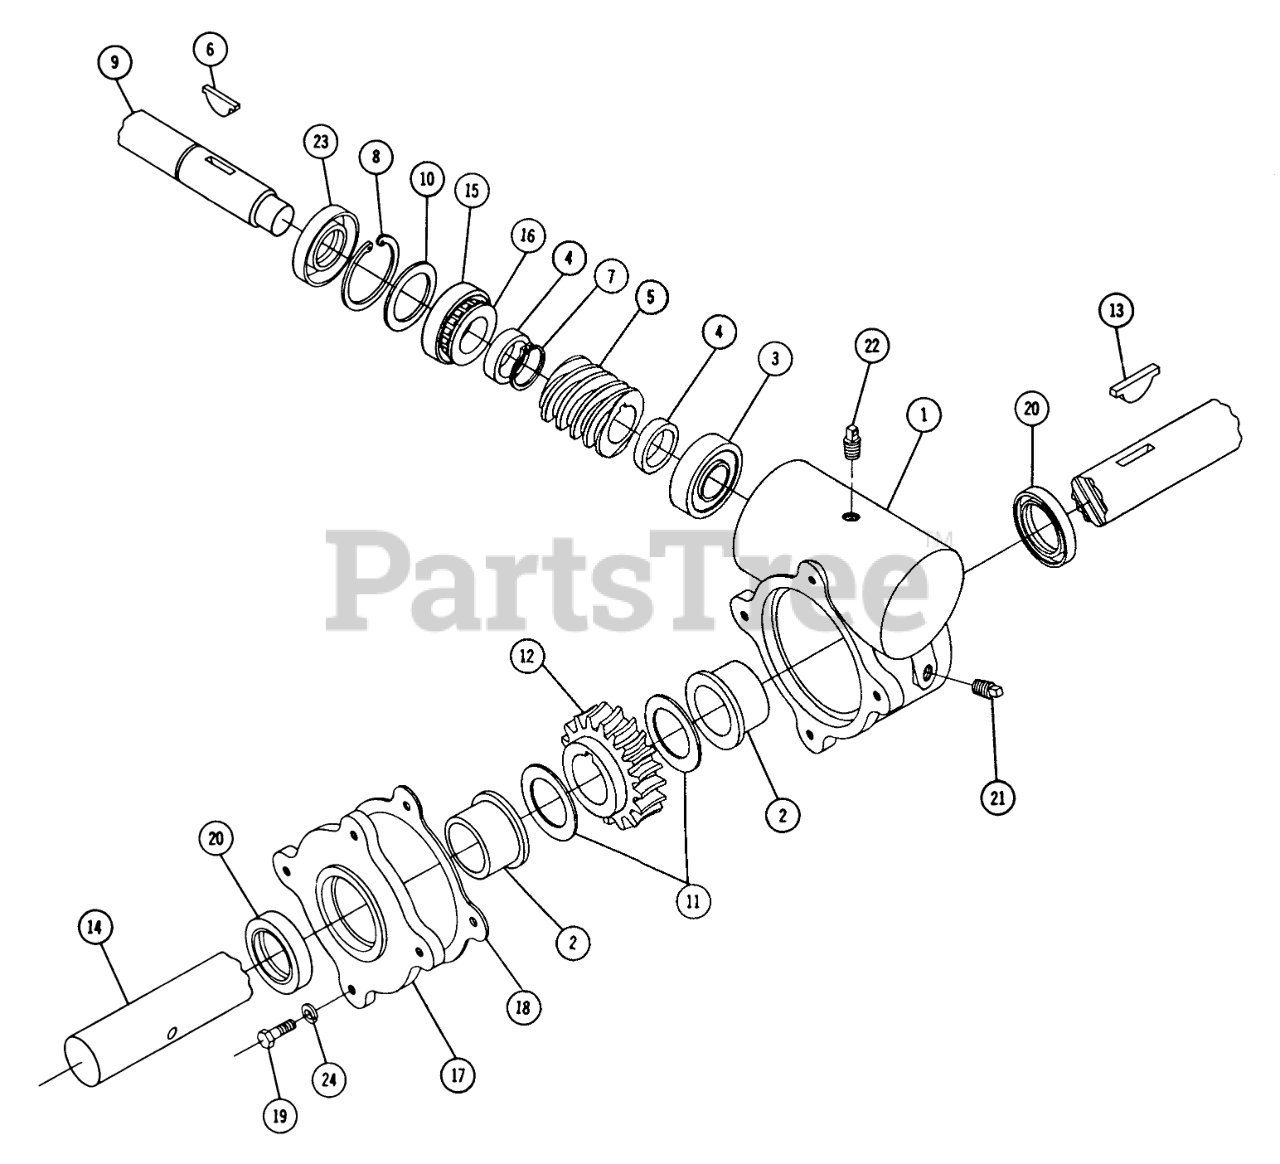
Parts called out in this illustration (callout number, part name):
1	Housing-Rotor Drive
2	Bushing-Sleeve
4	SPACER
8	Ring-Snap
9	Shaft-Impeller
11	Washer-Thrust
12	Gear-Worm
13	HI PRO KEY
16	BEARING CONE
17	Cover
18	GASKET
19	Bolt-1/4-20 x 5/8
20	Seal-Oil 1.00 Shaft
22	Plug-Vent
23	Seal-Oil .75 Shaft
24	Lockwasher
